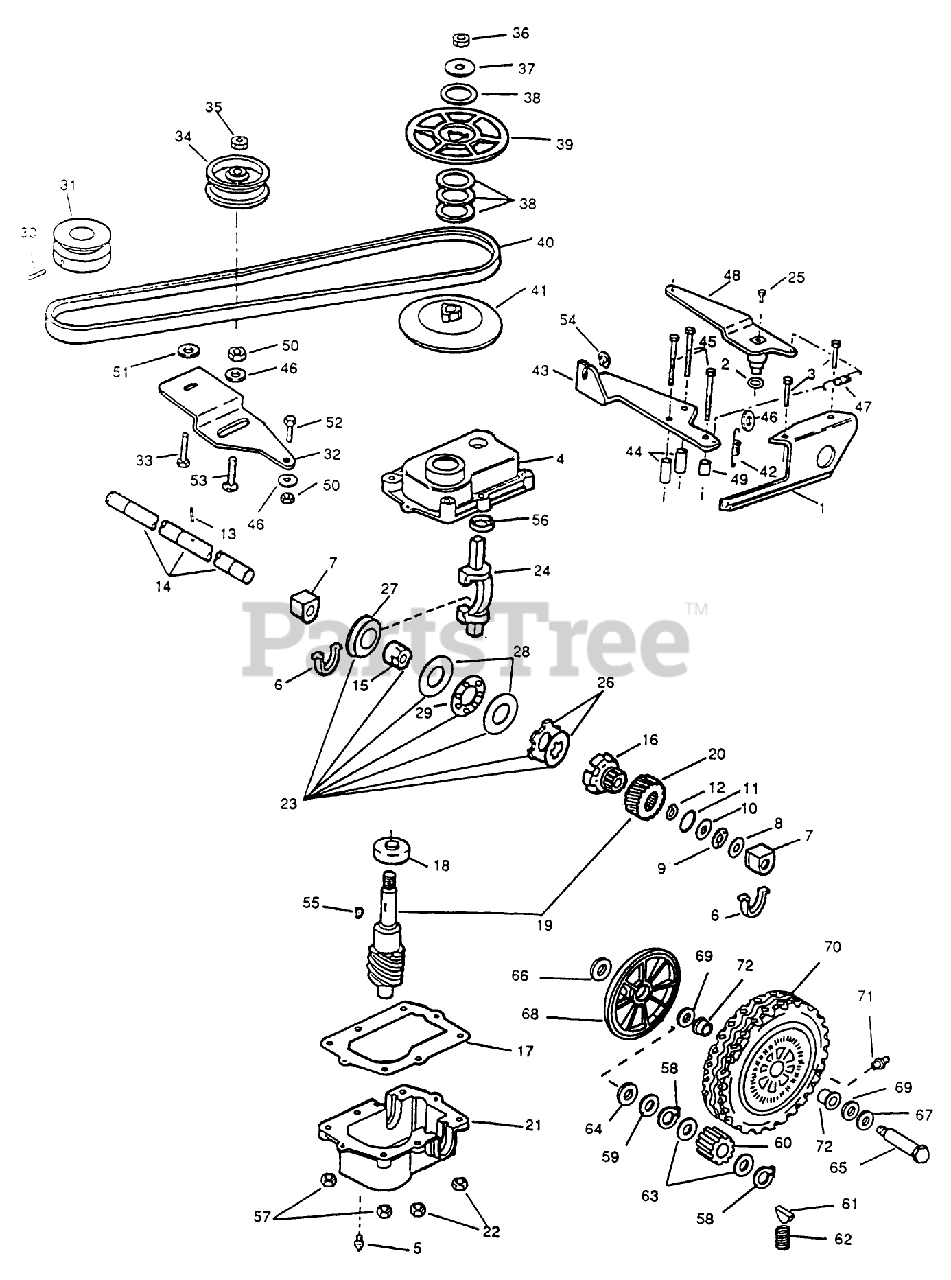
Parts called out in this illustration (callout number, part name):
2	O-RING
7	BEARING & SEAL AY (12)
8	THRUST WASHER
10	WASHER-THRUST
12	RET RING
13	PIN DRIVE LOCK
16	DRIVER BROCKWAY
17	GASKET HOOSIER
18	BEARING-BALL
20	WORM WHEEL
22	LOCKNUT E
24	FORK SHIFT
25	SCREW SEMS SM
26	Disc Plate Kit
27	Collar
30	SET SCREW
31	PULLEY - ENGINE
34	PULLEY IDLER NHI
35	NUT-JAM, LOCKING
36	LOCKNUT
37	WASHER
39	PULLEY UPPER PL
40	V-BELT F
41	PULLEY LOWER PL
42	SPRING EXTEN D&B
43	CONDUIT ANCHOR BRKT
46	WASHER S
47	SPRING
50	NUT-LOCK F
51	WASHER
54	RET. RING
55	KEY GALGER
56	GUIDE ELCO
57	LOCKNUT E
58	RET RING
59	THRUST WASHER
60	PINION BROCKWAY
61	KEY
62	SPRING
63	SPACER/GR ALGHNY
64	WASHER
65	BOLT WHEEL
66	WASHER
67	SPACER
69	WASHER-FELT
71	FITTING LINCOLN
